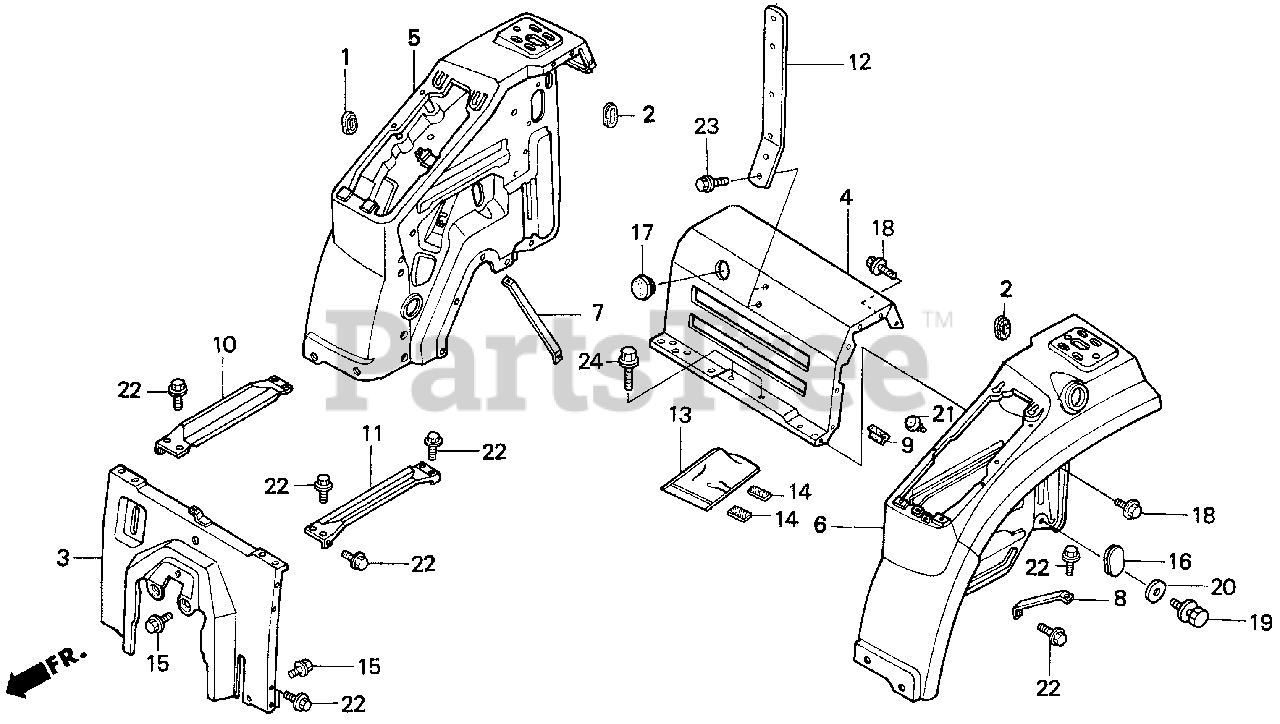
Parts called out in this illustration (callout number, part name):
1	CAP, DOOR WIRE HARNESS HOLE
2	GROMMET, TERMINAL COVER
3	COVER, RR. *R165* (JOLLY RED)
4	PANEL, RR. *R165* (JOLLY RED)
5	FENDER, R. RR. *R165* (JOLLY RED)
6	FENDER, L. RR. *R165* (JOLLY RED)
7	MEMBER, R. FENDER
8	MEMBER, L. FENDER
9	RUBBER, AUXILIARY CHANGE STOPPER
10	PANEL, R. SEAT SUPPORT *R165* (JOLLY RED)
11	PANEL, L. SEAT SUPPORT *R165* (JOLLY RED)
12	BRACKET, EMBLEM (SMVI)
13	BAG, OWNER'S MANUAL
14	TAPE, MAGIC (25X50) (FEMALE)
15	BOLT, ATAC SPINDLE STOPPER
16	PLUG, HOLE (36X65)
17	CAP, REMOTE CONTROL MIRROR HOLE
18	BOLT-WASHER (6X12)
19	BOLT-WASHER (8X16)
20	WASHER, PLAIN (8MM)
21	RUBBER B, STAND STOPPER
22	BOLT, FLANGE (6X12)
23	BOLT, FLANGE (6X16)
24	BOLT, FLANGE (8X14)
